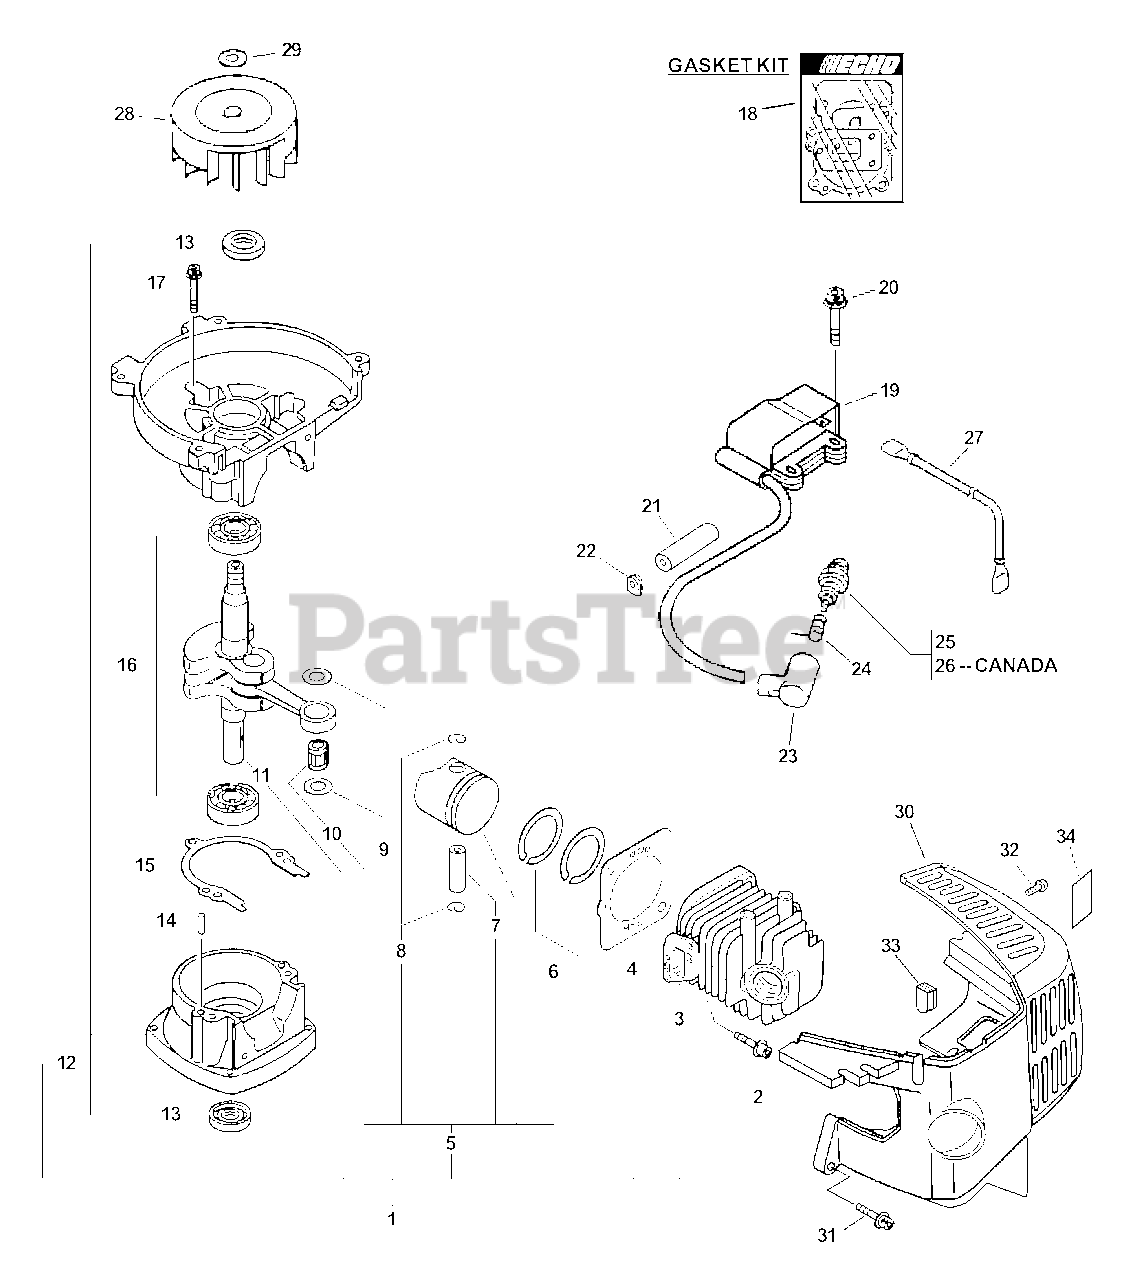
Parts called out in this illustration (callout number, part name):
1	SHORT BLOCK -- SB1068
2	SCREW - 4X22
3	CYLINDER
4	GASKET, CYLINDER
5	PISTON KIT
6	RING, PISTON
7	PIN, PISTON
8	RING, RETAINING
10	BEARING, NEEDLE - 8
11	CRANKSHAFT ASSY
12	CRANKCASE KIT
13	SEAL, OIL
14	PIN - LOCATING
15	GASKET, CRANKCASE
16	BEARING, BALL - 6201
17	SCREW - 5X28
18	GASKET KIT
19	COIL, IGNITION
20	SCREW - 4X20
21	TUBE, INSULATOR
23	CAP, SPARK PLUG
24	TERMINAL, SPARK PLUG CAP
25	SPARK PLUG -- BPM-8Y
26	SPARK PLUG -- BPMR-8Y
27	LEAD - IGNITION
28	WASHER - 8
29	FLYWHEEL
30	COVER, ENGINE
31	SCREW - 5X22
32	SCREW - 4X8
33	PLUG
34	LABEL - HOT SURFACE
